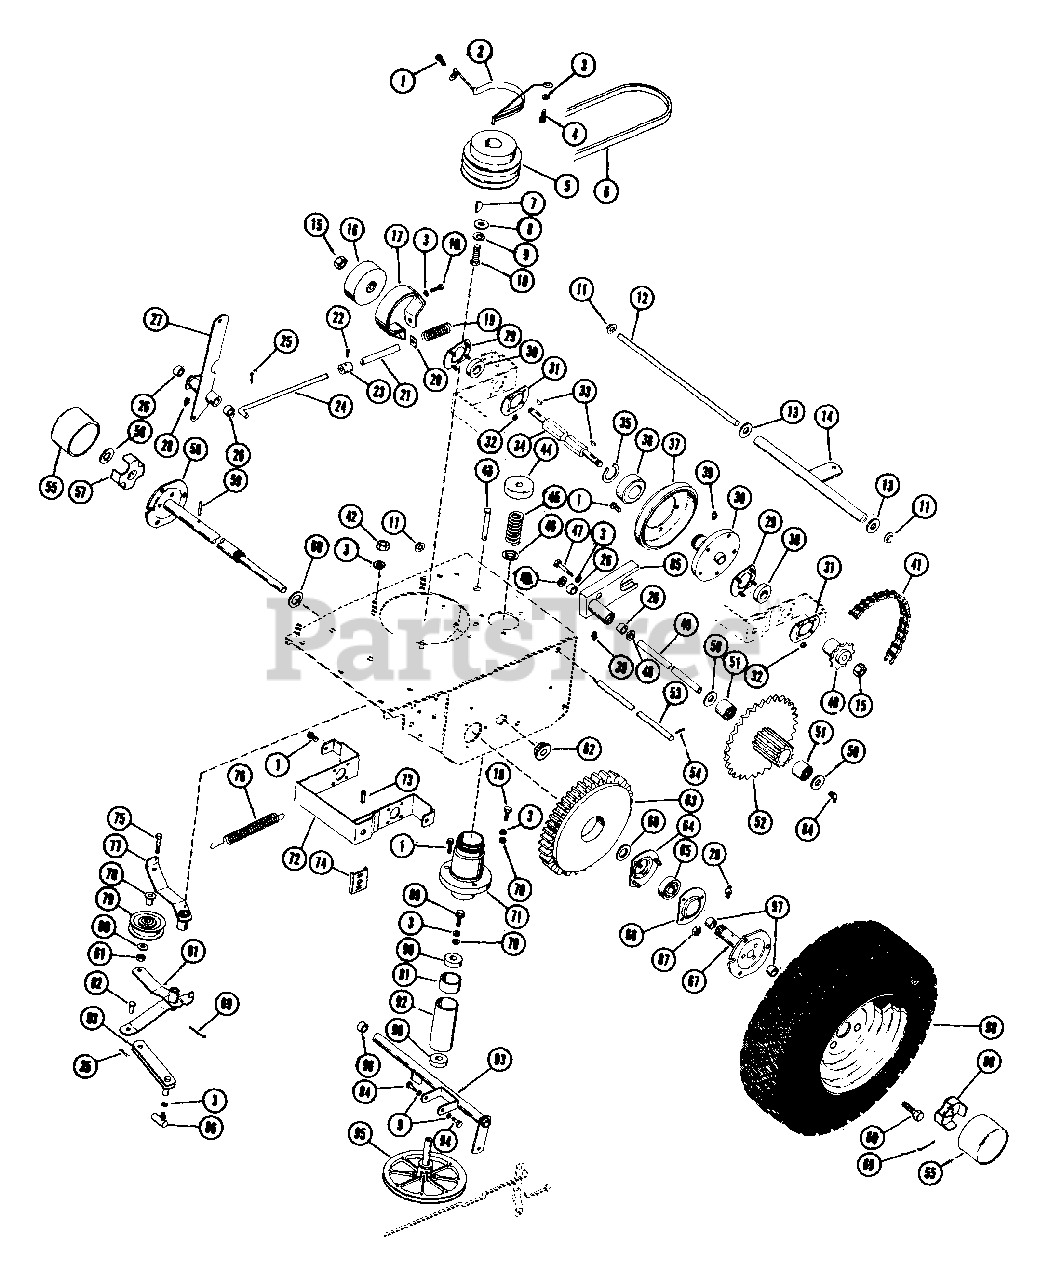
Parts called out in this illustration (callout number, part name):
1	BLT-SERHFWH .31-18X.50 PL
2	REAR BELT FINGER
3	WSHR-LK .312X.097 PL HVY
4	BLT-HEX .31-18X1.00 PL GR 2
5	ENGINE SHEAVE
6	V-BELT, SAE 380-RAW EDGE
7	KEY-WDRF .156X.625X.25 SAE 6
8	WSHR-FL-STL.406X.812X.065PL
8	WSHR-FL-STL .438X1.125X.19
9	WSHR-LK .375X.115 HVY PL
10	BLT-HEX .38-24X1.25 BLKO GR5
11	CAP, .50 ROD YWZC
12	HITCH SHAFT
13	WAVE WASHER .531X.781X.125FH
15	NUT-LK-CTR .50-20 PL
16	BRAKE DRUM
17	BRAKE BAND
18	BLT-HEX .31-18X.50 PL GR2
19	SG-COMP 1.75 FREE LENGTH
20	BRAKE BAND WASHER
21	BRAKE SPACER .5 X .4 X 2.63
22	SCR-SET .25-20X.50 SQHCUP HT
23	SET COLLAR
24	BRAKE ROD
25	PIN-COTR .09X.75 PL
26	BSHG-SLV .625X.750X.500 BR
27	BRAKE BELL CRANK
28	HYDRAULIC DRIVE FITTING
29	BEARING FLANGE
30	BRG-BALL .500X1.38X.437
31	BEARING FLANGE
32	NUT-KEPS 10-24 PL
33	KEY-WDRF .125X.625X.250 SAE5
34	HEX SHAFT
35	RG-RTNG-EXT 1.250X.050
36	BRG-BALL 1.25X2.18X.63
37	FRICTION DISC
39	ZERK FITTING
40	9 TOOTH SPROCKET
41	CHAIN
42	NUT-HEX .312-18
43	PIN-CLEVIS .500 X 3.250
45	SG-COMP .148X1.23X2.53 WLD87
46	SPRING RETAINER
47	BLT-HEX .31-24X.50 GR5
48	SEAL .625X.875X.125
49	CARRIER SHAFT
50	WSHR-FL-STL .630X1.005X.062 PL
51	BRG-NEEDLE .625X.812X.50
52	PINION & SPROCKET
53	DISC FORK ROD
54	PIN-ROLL .188X1.00
55	HUB CAP
56	PUSHNUT
57	SPINDLE CUP
58	R H AXLE SHAFT
59	PIN-ROLL .188X1.25
60	WSHR-FL-STL .880X1.380X.062
61	NUT-LK .312-18 GR A PL
62	FLANGE BUSHING
63	DIFFERENTIAL ASSEMBLY
64	BEARING FLANGE
65	BRG-BALL .876 X 1.750 X .50
66	BEARING FLANGE
67	L H AXLE ASSEMBLY
68	BLT-WHL .50-20X.50 GR5 PL
69	PIN-COTR .12X1.0 PL
70	WSHR-FL-STL.312X.734X.065PL
71	DRIVE SPRING HOUSING
72	CARRIER
73	PIN-ROLL .188X1.50
74	LOCATING PLATE
75	BLT-HEX .31-18X1.25 PL GR2
76	SG-TENS .063X.44X2.81 WLD 18
77	IDLER ARM
78	SPCR, BRG .315X.50X.688X.281
79	IDLER
80	WSHR-FL-STL .38X.875X.083 PL
81	SHIFT TRANSFER LEVER
82	CLEVIS PIN
83	SHIFT LINK
84	FRAME CHANNEL
85	SLIDING FORK
86	BALL JOINT
87	NUT-LK-FLG .250-20 PL
88	SPINDLE CUP
89	BLT-LK .31-18X.75 GR 5
90	BRG-BALL .625X1.375X.44
91	BEARING SPACER .87 X .63 X 1.2
92	DRIVE SPINDLE HOUSING
93	DISK FORK
94	SCREW PIN
95	DRIVE DISK ASSEMBLY
96	FORK SPACER
97	BSHG-SLV .562X.625X.625 BRZ
98	TIRE & WHEEL ASSEMBLY
98	TURF SAVER TIRE & WHEEL ASSEMB
